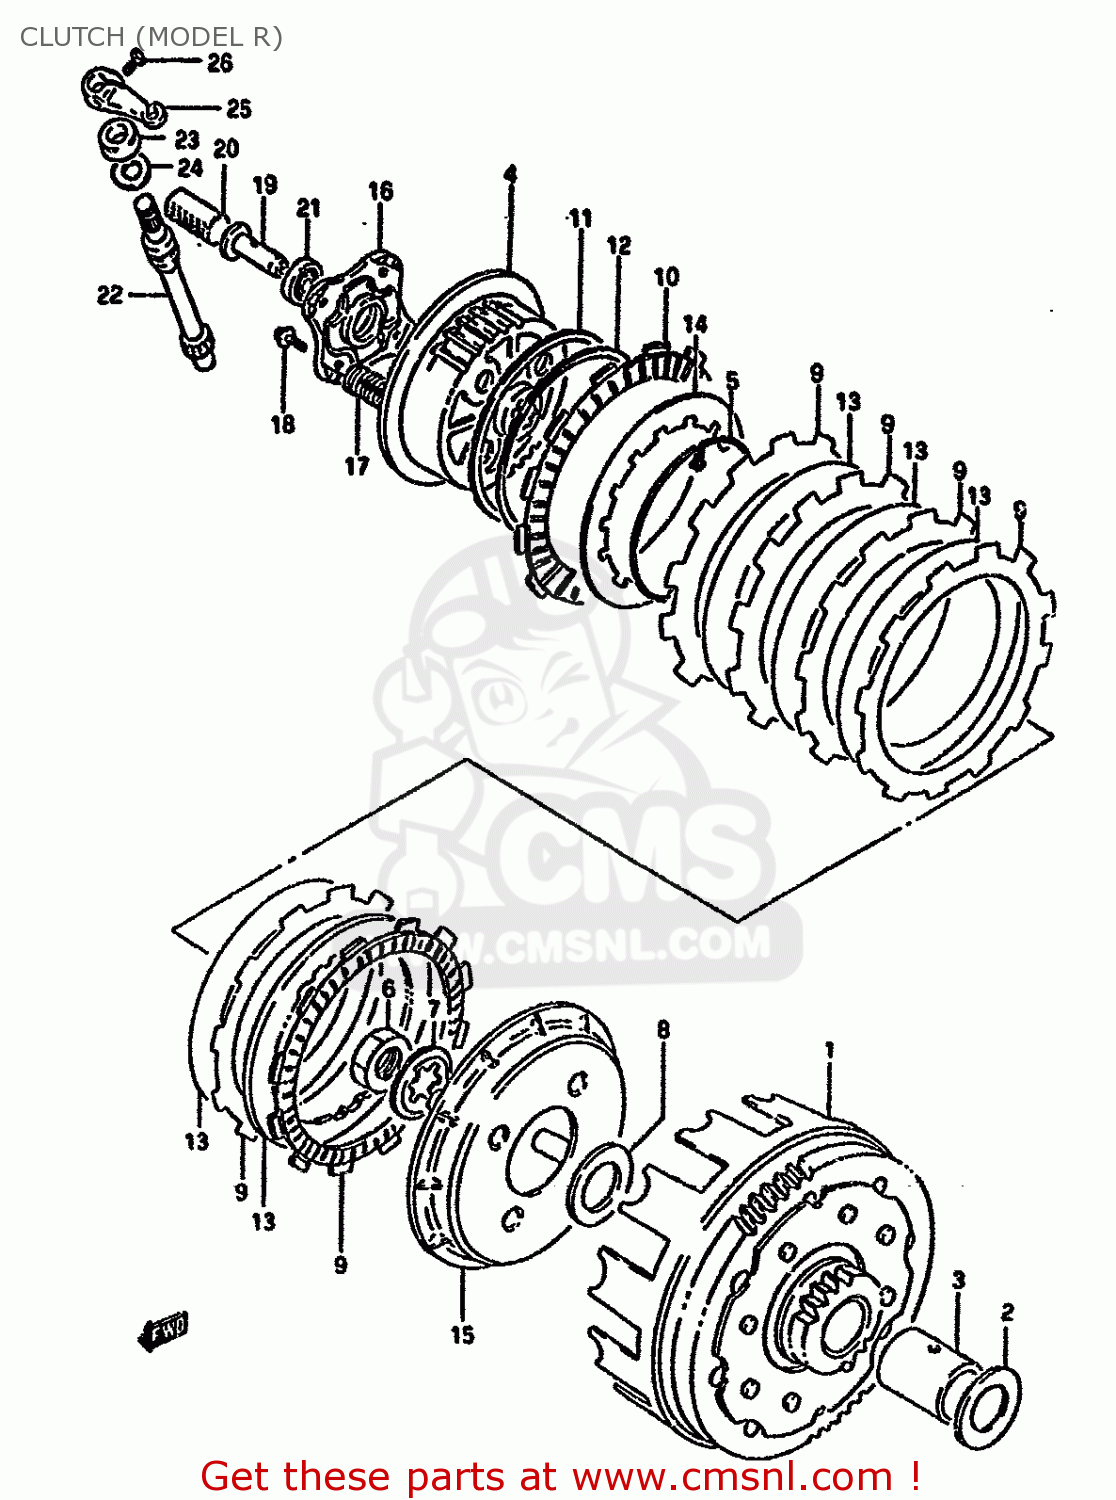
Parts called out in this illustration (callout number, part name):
1	GEAR ASSEMBLY,PRIMARY DRIVE
2	WASHER
3	SPACER(22X28X32.5)
4	HUB,CLUTCH SLEEVE
5	RING,WAVE WASHER STOPPER
6	NUT
7	WASHER,LOCK
8	WASHER
9	PLATE,CLUTCH DRIVE (NAS)
10	PLATE,CLUTCH DRIVE NO (NAS)
11	SEAT,WAVE WASHER
12	WASHER
13	PLATE,CLUTCH DRIVEN (NAS)
14	PLATE,CLUTCH DRIVEN (NAS)
15	DISC,CLUTCH PRESSURE
16	PLATE,RELEASE
17	SPRING
18	BOLT
19	PIECE,CLUTCH PUSH
20	RACK,CLUTCH RELEASE
21	BEARING
22	PINION,CLUTCH RELEASE
23	SEAL,OIL (12X22X9)
24	WASHER (14.2X22X1)
25	ARM,CLUTCH RELEASE
26	BOLT
